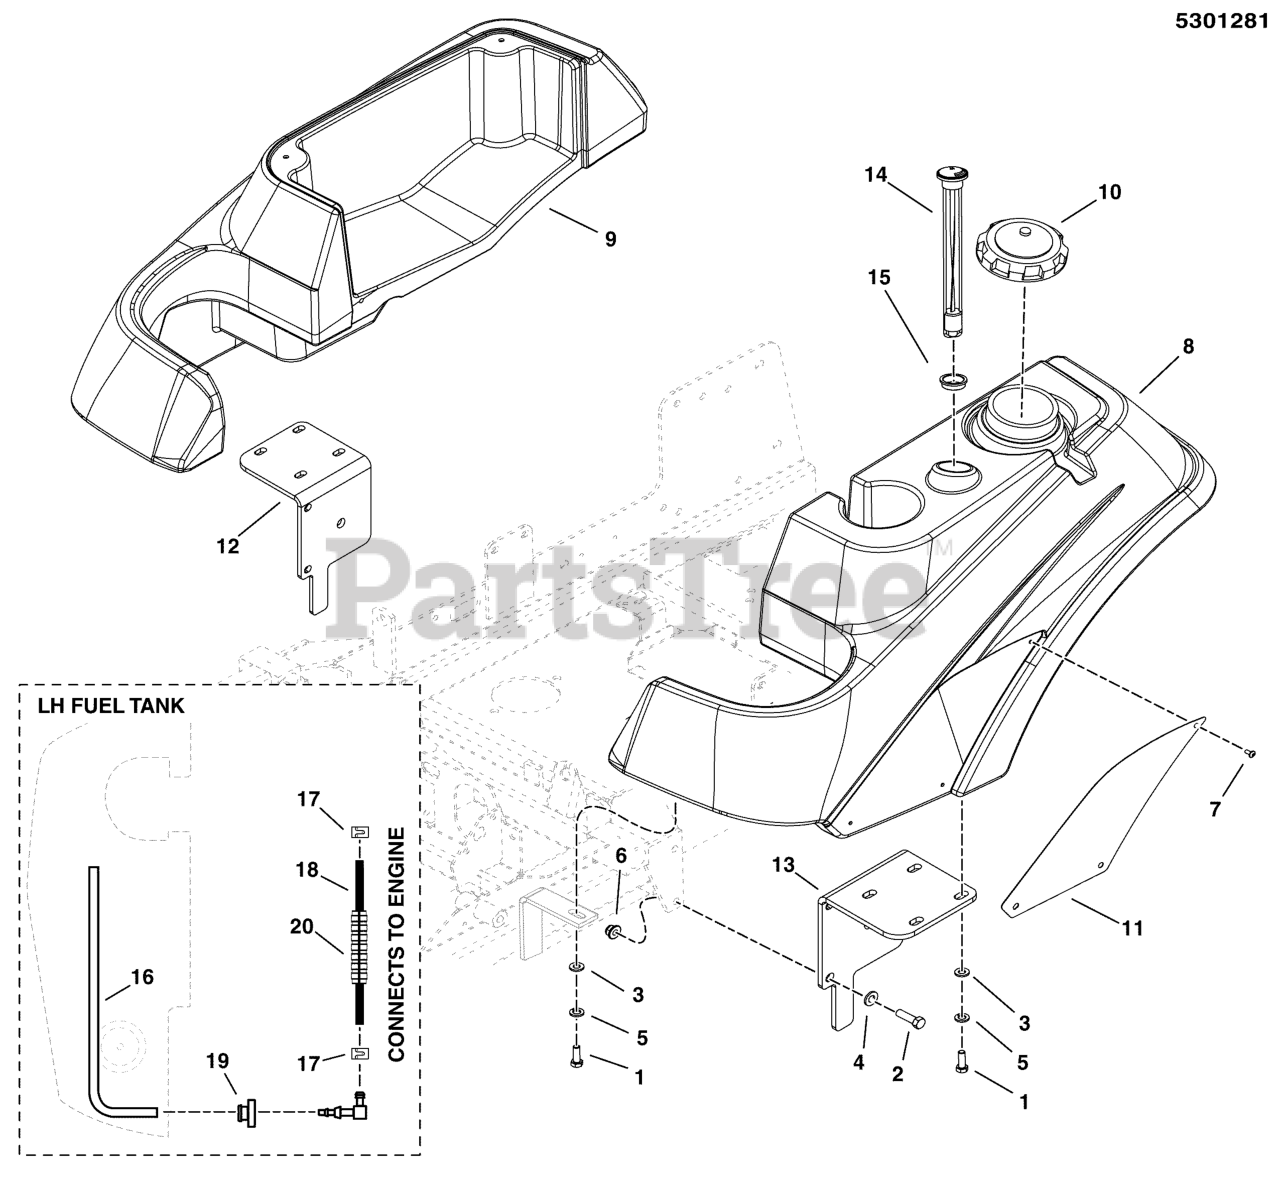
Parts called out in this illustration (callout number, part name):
1	BOLT, 5/16-18 X 1" GRD5 YZ
2	BOLT, 3/8-16 X 1" GD5 CZ
3	WASHER, 5/16" SAE
4	WASHER, 3/8 SAE
5	WASHER, 5/16 LOCK CZ
6	NUT, 3/8 - 16 HEX NYLOCK FLANGE
7	SCREW, Allen Head, #10-24 x 3/8"
8	TANK, FUEL, LH
8	TANK, FUEL, IS1500Z/IS500Z - LH
9	TANK, FENDER, CITATION/ZT4000 - RH
10	CAP, GASOLINE, VENTED
10	FUEL CAP, 3-1/2", MANAGED VENT OUT, 12"
11	PLATE, BADGE - IS1500 - RED
12	WELD, TANK MOUNT - BLK
13	WELD, TANK MOUNT - LH - BLK
14	GAUGE, FUEL, 12
15	GROMMET, FUEL GAUGE (SV)
16	PICKUP TUBE ASM, FUEL TANK, 22"
17	CLAMP, Hose
18	1/4" Fuel Line, 14" Long
18	1/4" Fuel Line, 8" Long
19	BUSHING-FUEL TANK RED RUBBER
20	WIRE LOOM, 1/2 ID, 11.00 LONG
20	WIRE LOOM, 1/2 ID X 5 IN
